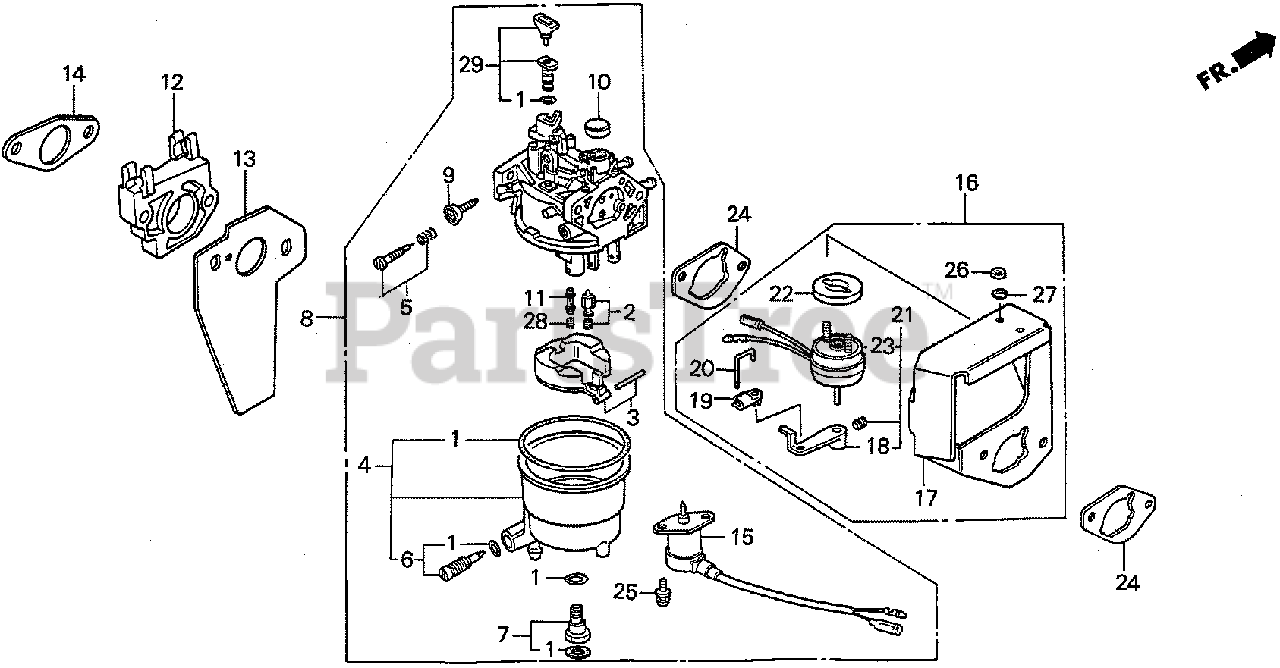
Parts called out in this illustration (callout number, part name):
1	GASKET SET
2	VALVE SET, FLOAT
4	CHAMBER SET, FLOAT
5	SCREW SET, PILOT
6	SCREW SET, DRAIN
8	CARBURETOR ASSY. (BE38A B)
8	CARBURETOR ASSY.
8	CARBURETOR ASSY. (BE38A D)
9	SCREW, THROTTLE STOP
10	CAP, CHOKE LEVER DUST
11	NOZZLE, MAIN
12	INSULATOR, CARBURETOR
13	GASKET, CARBURETOR
14	GASKET, INSULATOR
15	VALVE ASSY., SOLENOID
16	STAY ASSY., SOLENOID
17	STAY, CHOKE SOLENOID
18	LEVER, CHOKE SOLENOID
19	JOINT, ROD
20	ROD, CHOKE SOLENOID
21	SOLENOID ASSY., CHOKE
22	SPACER, CHOKE SOLENOID
23	SOLENOID, ROTARY CHOKE
24	GASKET, AIR CLEANER
25	SCREW-WASHER (5X12)
26	NUT, HEX. (3MM)
27	WASHER, SPRING (3MM)
28	JET, MAIN (#92)
28	JET, MAIN (#95)
28	JET, MAIN (#98)
29	JET SET, PILOT (#38)
